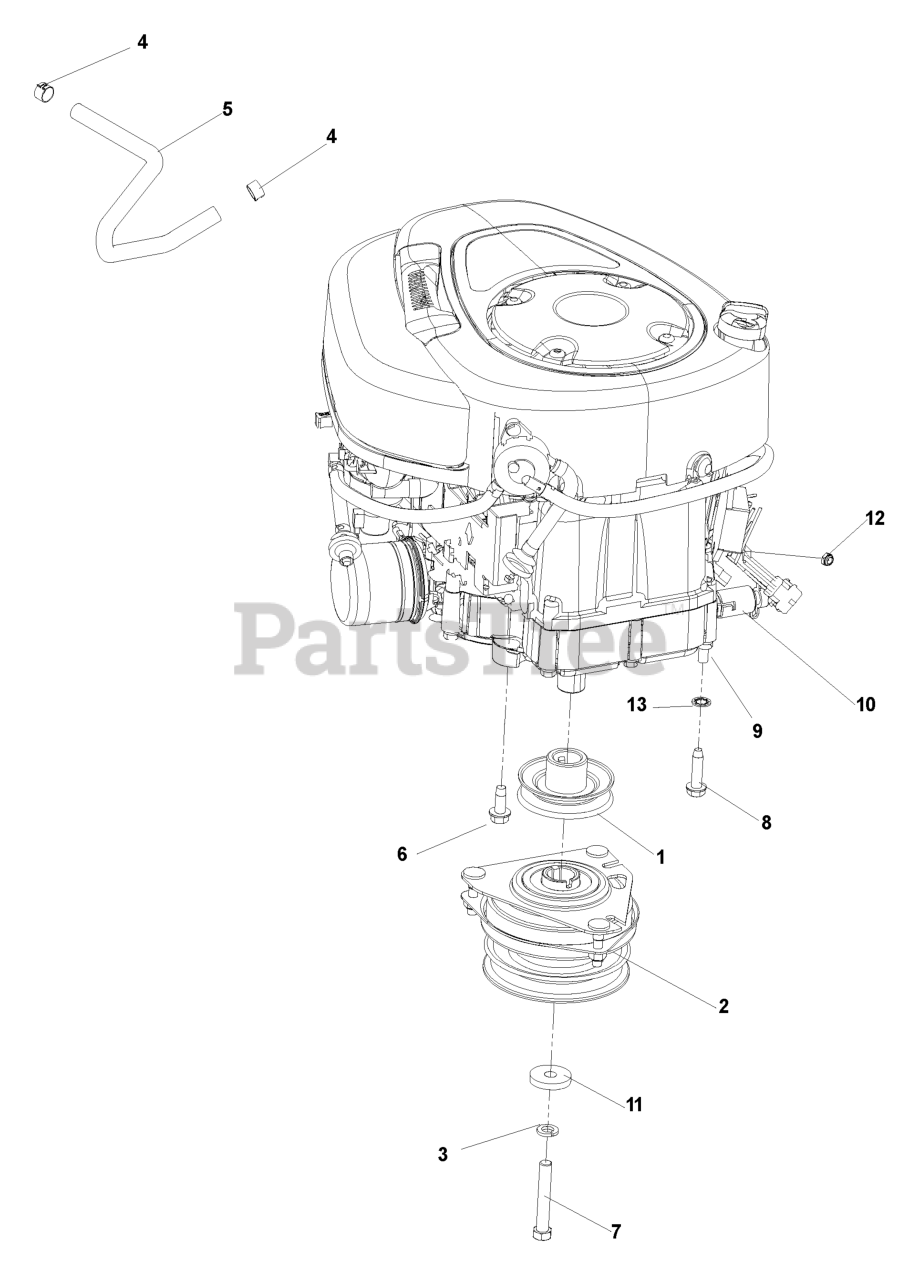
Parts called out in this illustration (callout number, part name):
2	CLUTCH 90 FT/LB OGURA
3	WASHER 7/16 LOCK
4	HOSE CLAMP
5	FUEL LINE 5"
6	BOLT 3/8-16 X 1.0
7	HEX SCREW 7/16-20 X 3
8	BOLT 3/8-16 X 1 1/2 ZINC CLEAR
9	NUT 3/8C CENTERBLOCK
10	OIL DRAIN FITTING
11	CLUTCH, WASHER
12	JAM NUT 1/4C (2 2 PW01)
13	WASHER
